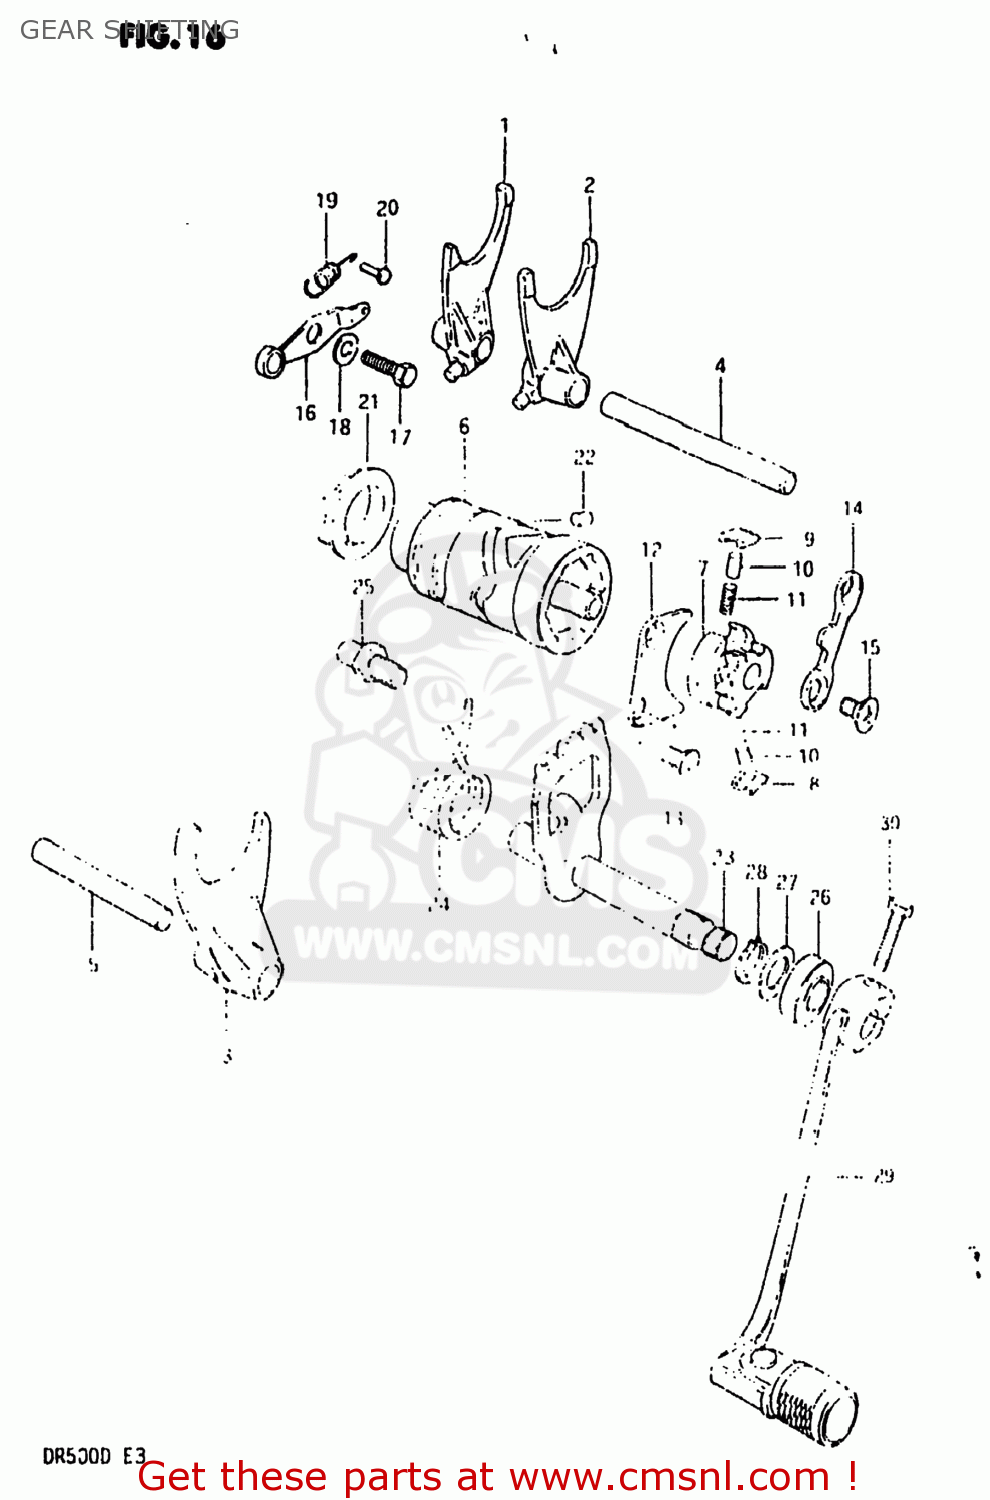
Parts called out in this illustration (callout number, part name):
1	FORK,GEAR SHIFT NO.1
2	FORK,GEAR SHIFT NO.2
3	FORK,GEAR SHIFT NO.3
4	SHAFT,GEAR SHIFT FORK
5	SHAFT,GEAR SHIFT FORK
6	CAM,GEAR SHIFT
7	RETAINER,GEAR SHIFT CAM
8	PAWL,GEAR SHIFT NO.1
9	PAWL,GEAR SHIFT NO.2
10	PIN(5X8)
11	SPRING
12	LIFTER,GEAR SHIFT PAWL
13	SCREW
14	STOPPER,GEAR SHIFT POLE
15	SCREW
16	STOPPER,GEAR SHIFT CAM
17	BOLT
18	WASHER
19	SPRING
20	RIVET
21	PLATE,SHIFT CAM STOPPER
22	PIN 4X6
23	SHAFT,GEAR SHIFT
24	SPRING
25	STOPPER,GEAR SHIFT CAM
26	OIL SEAL
27	WASHER
28	CIRCLIP
29	LEVER ASSEMBLY,GEAR SHIFTING
30	BOLT
